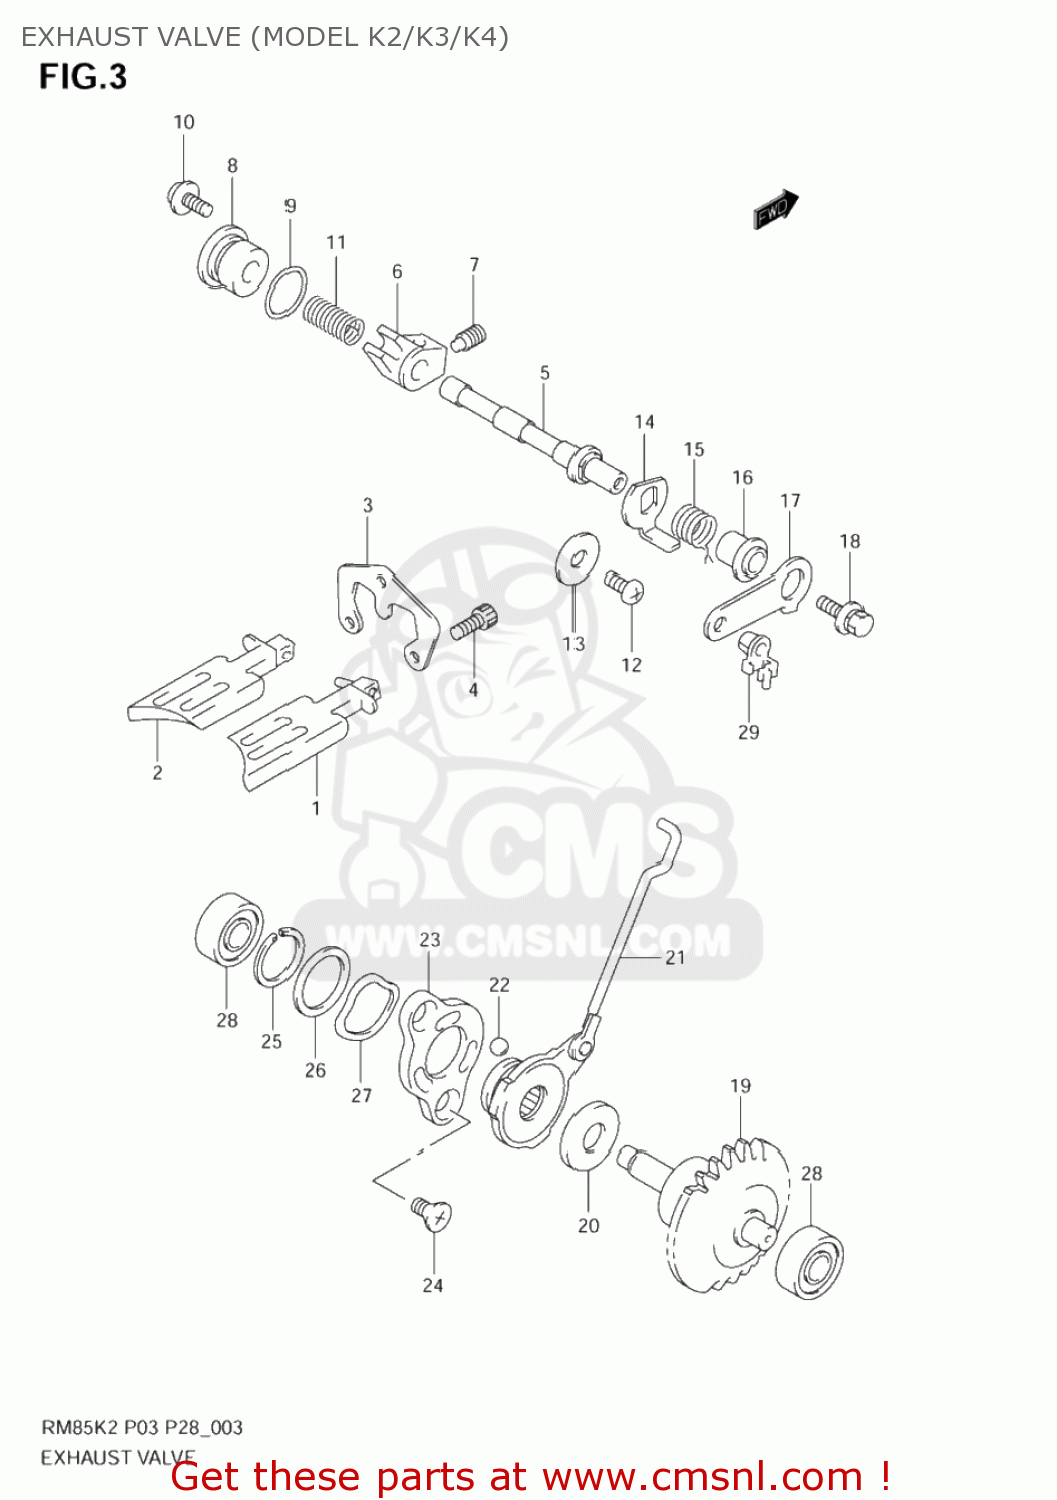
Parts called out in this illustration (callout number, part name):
1	VALVE,EXHAUST,R
2	VALVE,EXHAUST,L
3	PLATE,EXHAUST VALVE
4	BOLT
5	SHAFT,EXHAUST VALVE
6	ARM,EXHAUST VALVE SHAFT
7	SCREW(6X10)
8	CAP,EXHAUST VALVE
9	O RING(D:1.9,ID:14.5)
10	BOLT
11	SPRING
12	SCREW
13	WASHER
14	LEVER,EXHAUST VALVE NO.2
15	SPRING
16	SPACER,EXHAUST VALVE
17	LEVER,EXHAUST VALVE NO.1
18	BOLT(5X12)
19	GOVERNOR ASSY,EXHAUST VALVE
20	BEARING(10X22X2.8)
21	ACTUATOR,EXHAUST VALVE
22	BALL
23	STARTER,EXHAUST VALVE ACTUATOR
24	SCREW(5X10)
25	CIRCLIP
26	SHIM(19.1X25X0.3)
27	WASHER
28	BEARING(8X22X7)
29	BUSH,EXHAUST VALVE ROD NO.1
